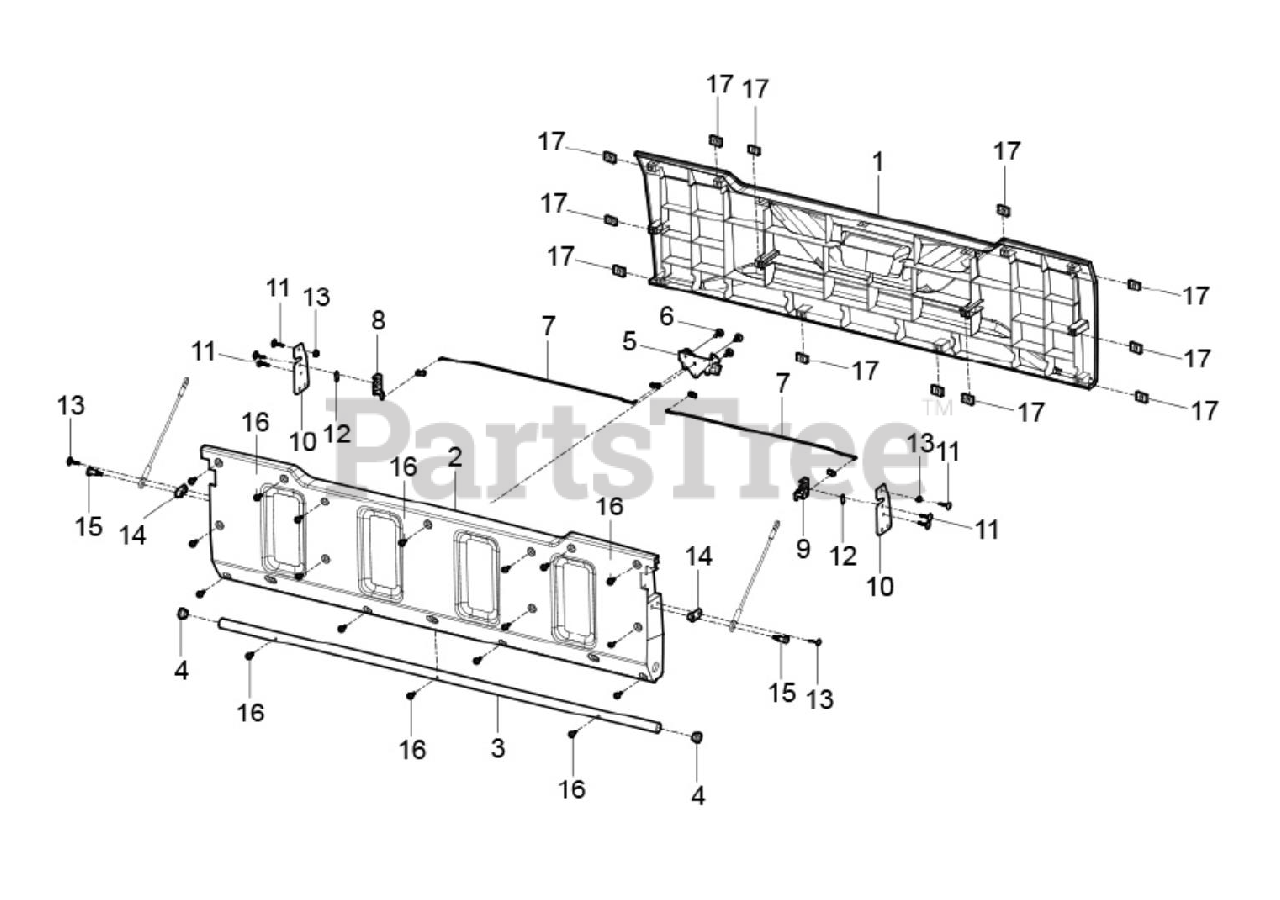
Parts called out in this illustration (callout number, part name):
1	CARGO BED DOOR
1	CARGO BED DOOR YELLOW
1	CARGO BED DOOR BLUE
1	CARGO BED DOOR BLACK
1	CARGO BED DOOR G2 CAMO
2	CARGO BED DOOR INSIDE PANEL
3	CARGO BED DOOR HINGE TUBE
4	BUSHING PLASTIC 10.5x18
5	CARGO BED LOCK ASSEMBLY
6	Cross Recessed Plate Head Screw M6x12
7	ROD - CARGO BED DOOR LOCK
8	CARGO BED DOOR LOCK KIT RH
9	CARGO BED DOOR LOCK KIT LH
10	DOOR LOCKING PLATE
11	Cross Large Plate Head Screw M6x16
12	Pan head screw with cross recess M6x30
13	HExAGON FLANGE HEAD NUT M6
14	DOOR LOCK STRAP PLATEDII
15	BOLT HExAGON SOCKET SHOULDER M8x18-10x9
16	Socket Hex Flat Head Bolt M6x16
17	CLAMP NUT M6x6
18	DOOR LOCK ADJUSTMENT GASKET
